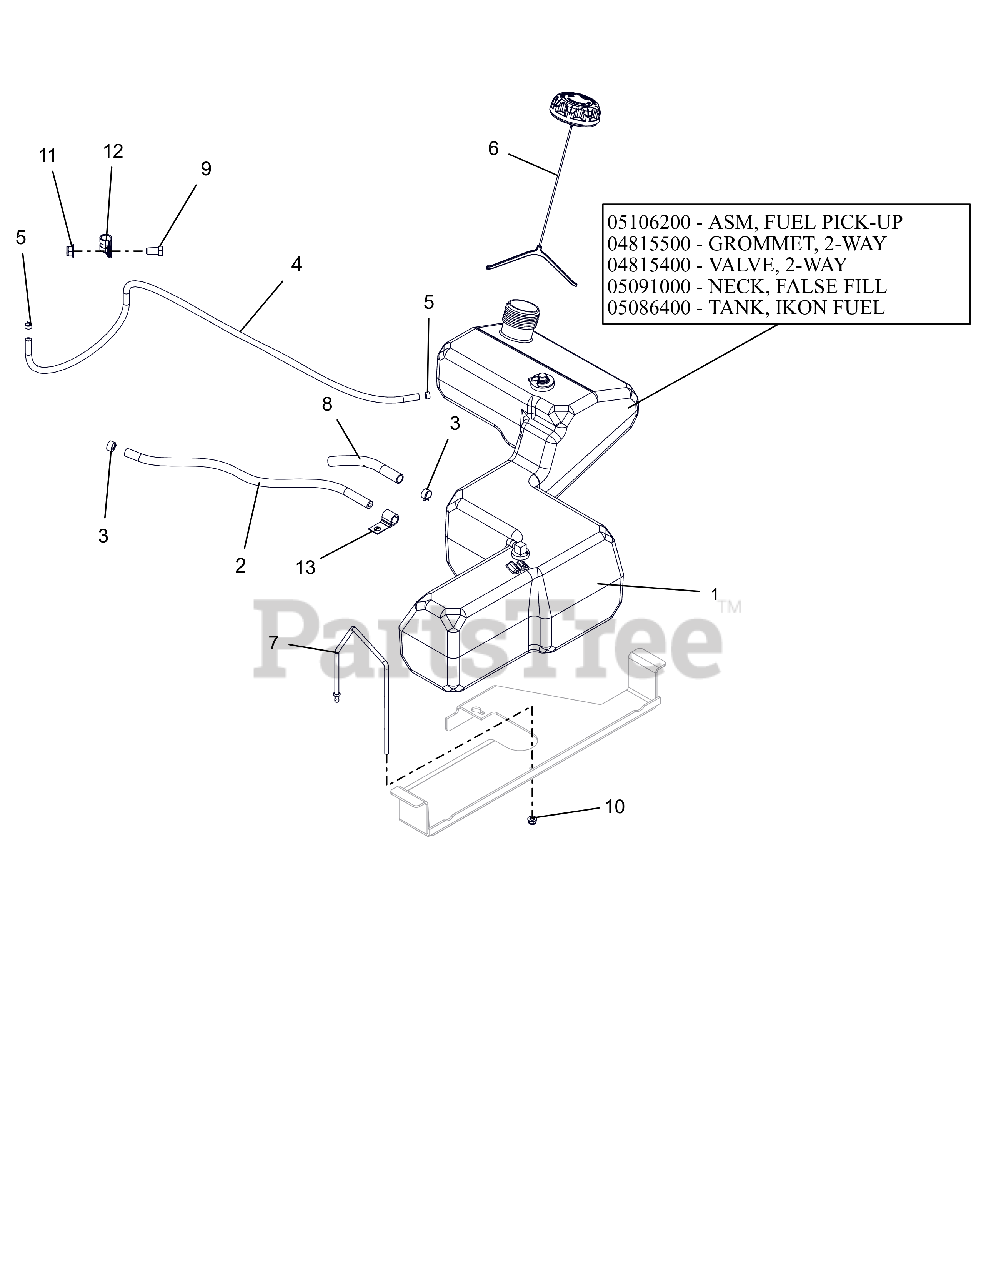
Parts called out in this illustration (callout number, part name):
1	ASSEMBLY, FUEL TANK IKON(2017)
1	ASM, IKON FUEL PICK-UP
1	GROMMET, 2-WAY
1	VALVE, 2-WAY
1	NECK, FALSE FILL-2017 IKON
1	TANK, IKON FUEL (2017)
2	HOSE, .25 LOW-PERM BULK GAS
3	CLAMP, FUEL LINE
4	HOSE, .188 LOW-PERM BULK GAS
5	CLAMP-HOSE, SPRING .188
6	CAP, FUEL VENT-IN 2.25" RATCH.
7	BRKT, FUEL TANK HOLD DOWN
8	WRAP, ANTIABRASION .5X.064WALL
9	@BLT-HEX .38-16X.75 GR5 YWZC
10	@NUT-LK-NYL-FLG .25-20 YWZC
11	@NUT-LK-NYL-FLG .38-16 YWZC
12	CLAMP, CUSHIONED STEEL
13	J-CLAMP
